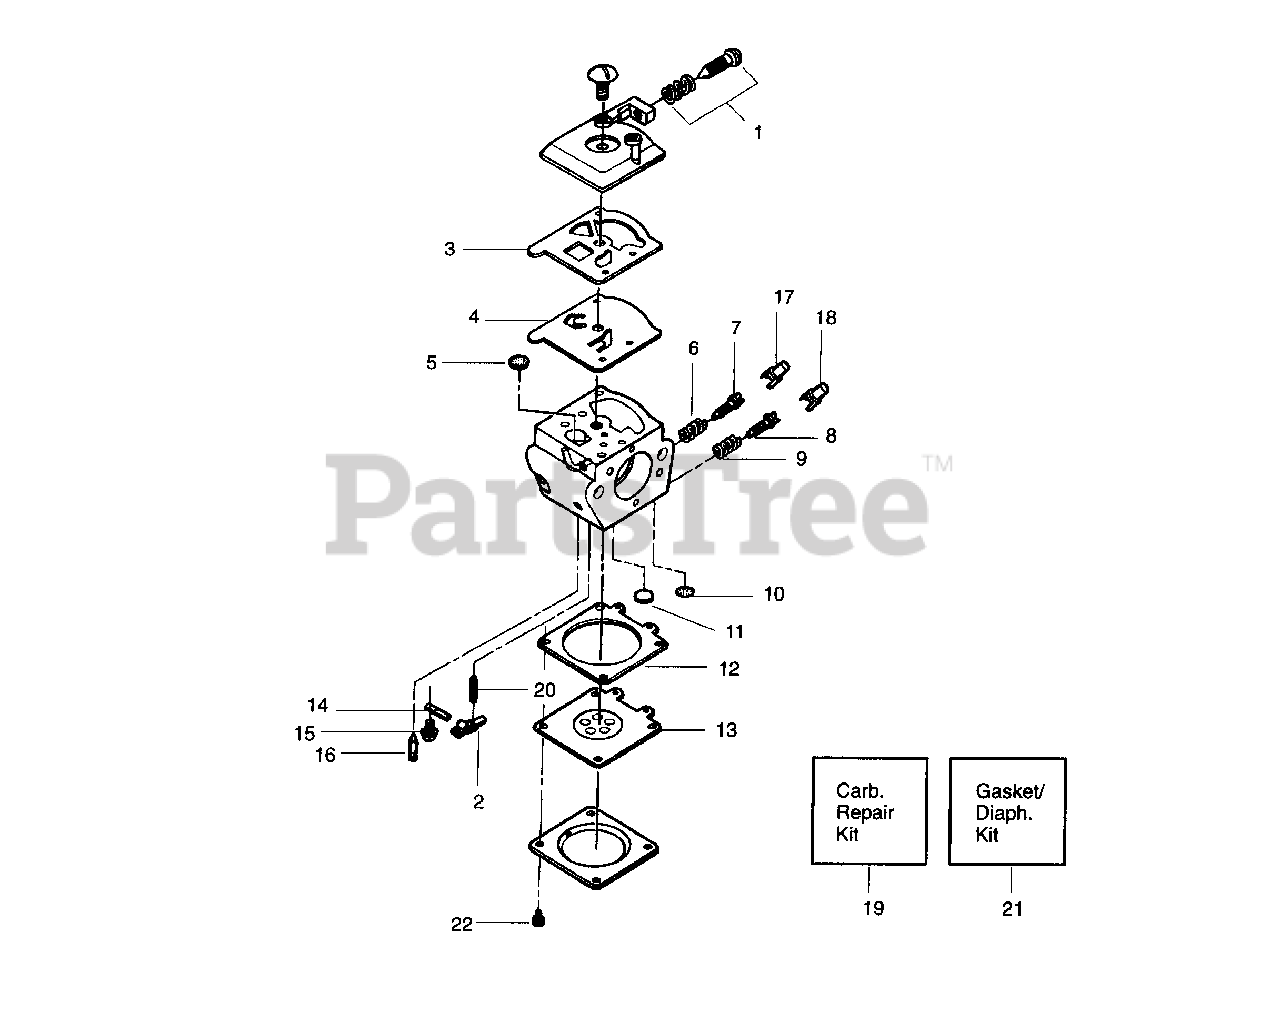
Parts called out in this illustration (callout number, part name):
1	Idle Adv. Screw Kit
2	Metering Lever
3	Fuel Pump Gasket
4	Fuel Pump Diaphragm
5	Fuel Inlet Screen
6	Needle Spring (Low Speed)
7	Low Speed Needle
8	Needle High Speed
9	Needle Spring (High Speed)
10	Welch Plug (5/16)
12	Metering Diaphragm Gasket
13	Metering Diaphragm
14	Metering Lever Pin
15	Metering Lever Pin Screw
16	Inlet Needle Valve
17	Limiter Cap High
18	Limiter Cap Low
19	Carburetor Repair Kit
20	Metering Spring Lever
21	Gasket Diaphragm Kit
22	Metering Cover Screw Ass'y
